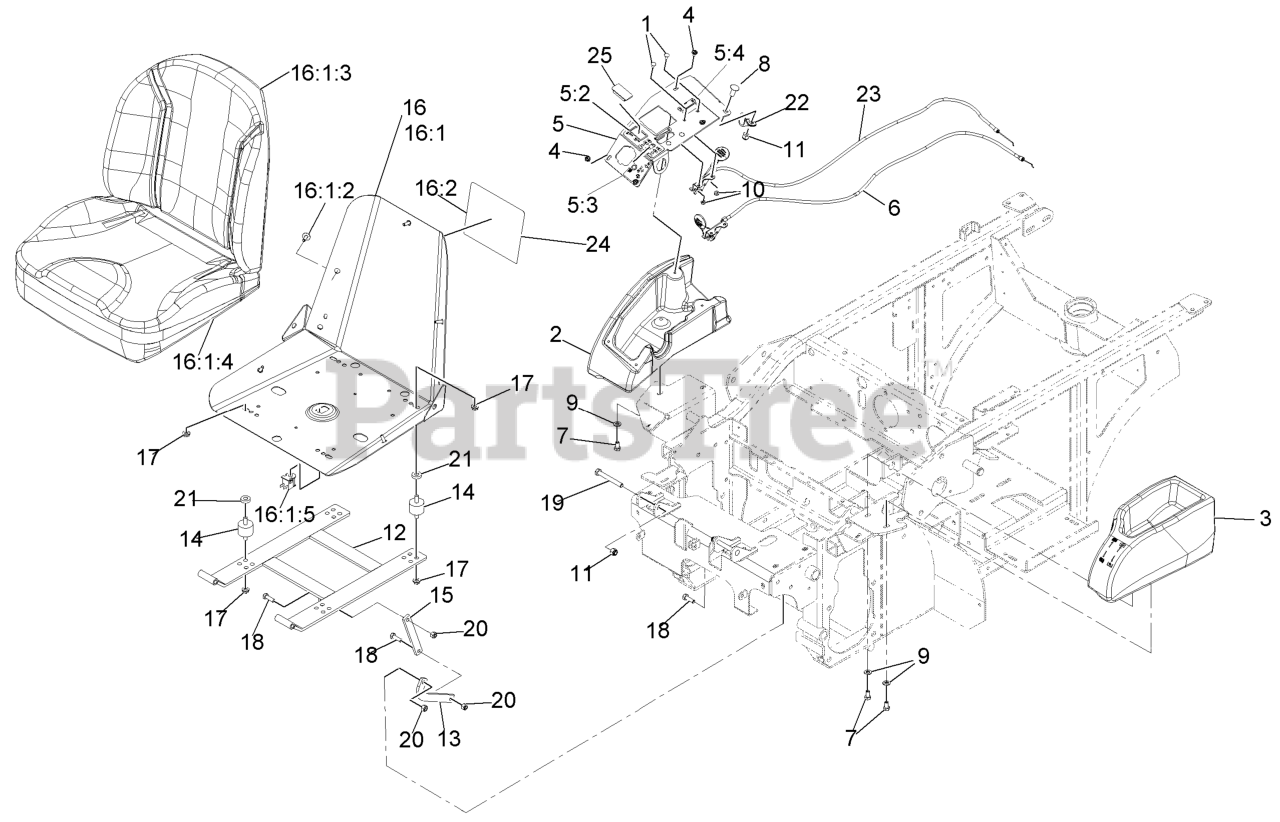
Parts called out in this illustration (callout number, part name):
1	BOLT-CARR
2	CONSOLE-RH
3	CONSOLE, LH GREY
4	SCREW-PPH
5	CONTROL PANEL ASM
5:2	Decal-Nav Console 640Kc
5:3	DECAL-SPEED CONTROL
5:4	DECAL-CHOKE
6	CABLE-THROTTLE
7	SCREW-HH
8	SCREW-CARR
9	WASHER-PLAIN
10	NUT-LOCK, NI
11	NUT-LOCK, NI
12	FRAME-SEAT
13	LINK-SEAT STOP
14	MOUNT-VIBRATION, RUBBER
15	LINK-SEAT
16	ASM-SEAT W/DECAL
16:1	ASM-Seat, Navigator
16:1:2	BOLT-SEAT
16:1:3	CUSHION-SEAT, BACK
16:1:4	COVER-SEAT BOTTOM SVC
16:1:5	SWITCH-BAIL
16:2	Decal-Service Aid
18	SCREW-HH
19	SCREW-HH
20	NUT-LOCK, NI
21	SPACER
22	CLIP-LOOM
23	CABLE-CHOKE
24	Decal-Service Aid
25	PLUG-HOLE
